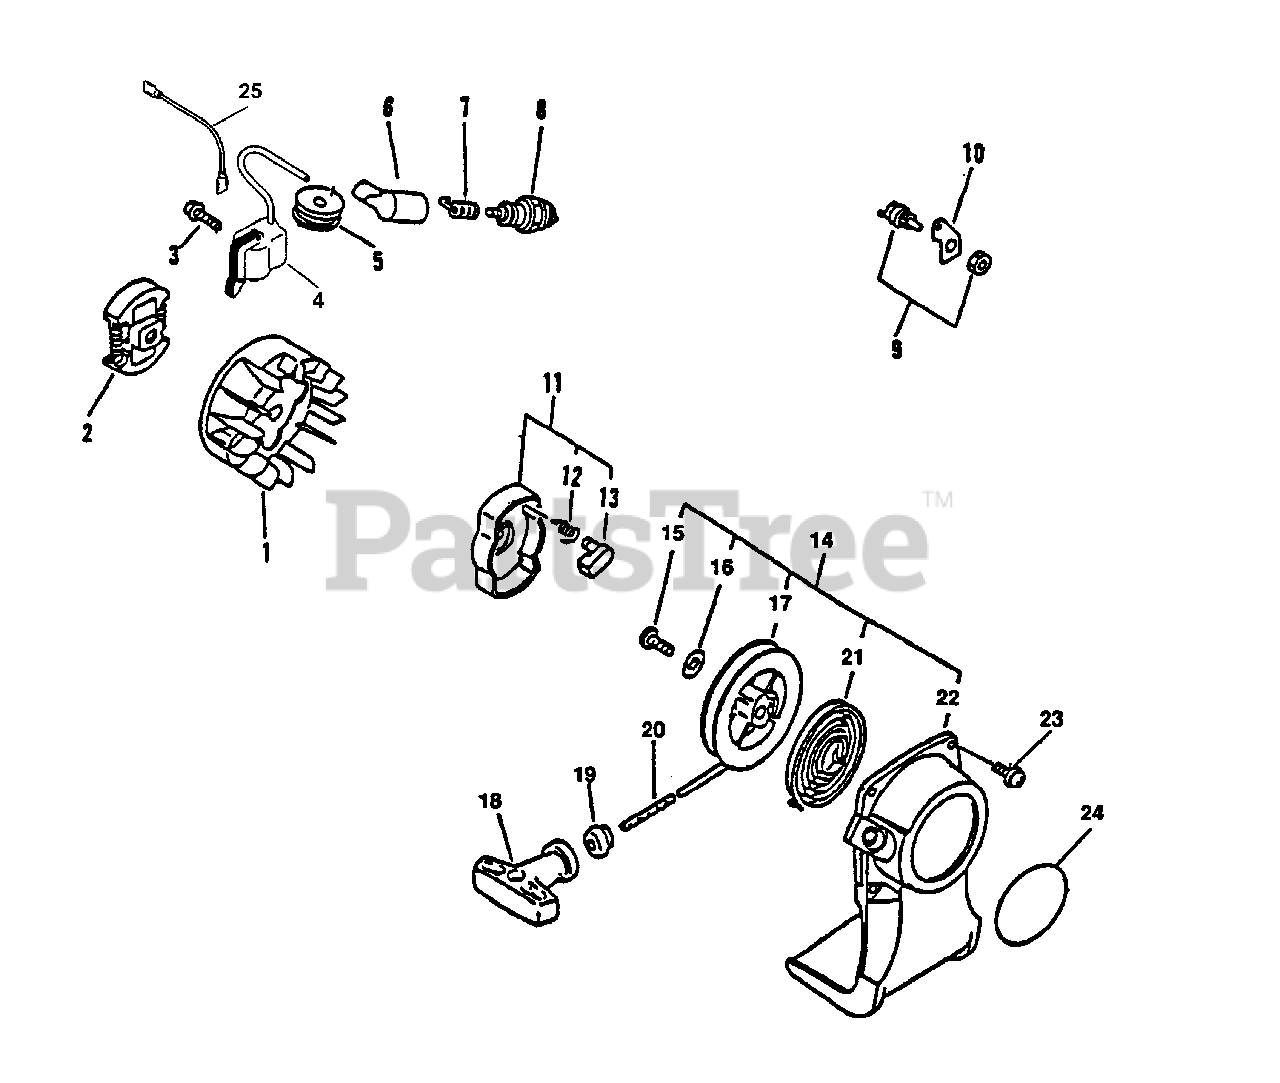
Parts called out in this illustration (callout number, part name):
1	FLYWHEEL
2	CLUTCH ASSY
3	SCREW 4×22
4	COIL, IGNITION
6	CAP, SPARK PLUG
7	TERMINAL, SPARK PLUG
8	SPARK PLUG - BPM7A
8	SPARK PLUG - BPMR7A
9	SWITCH, ON-OFF
10	BRACKET, SWITCH
11	PAWL ASSY, STARTER
12	SPRING, RETURN
13	PAWL, STARTER - BLACK
14	STARTER ASSY
15	SCREW
16	WASHER
17	REEL, ROPE
18	GRIP, STARTER
19	GUIDE, ROPE
21	SPRING, RECOIL
22	CASE, STARTER
23	BOLT 4×16
24	LABEL, ECHO
25	LEAD - GROUND
